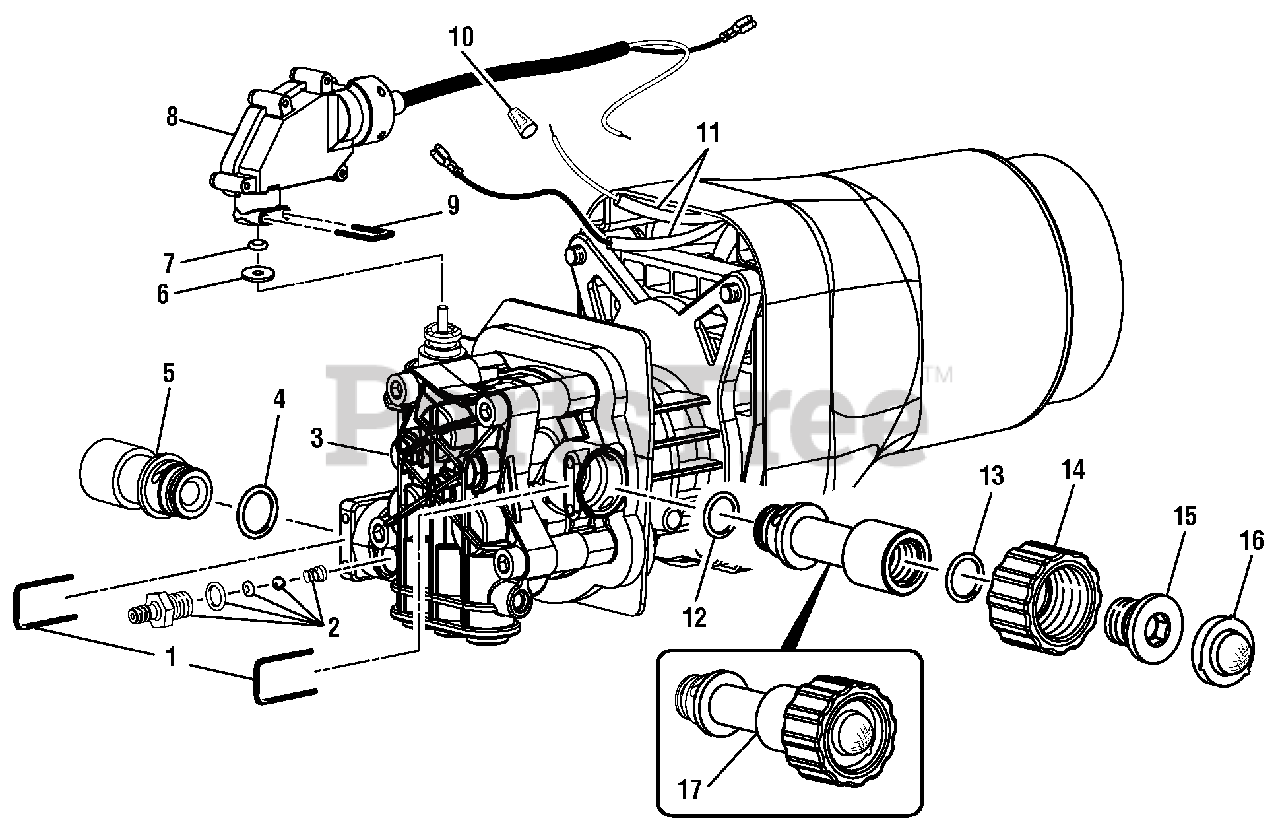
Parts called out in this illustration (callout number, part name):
2	Detergent Nipple Assembly
3	Motor and Pump Assembly
5	Outlet Tube Assembly
6	Washer (Brass)
7	O-Ring
8	Pressure Switch
14	Water Inlet Connector
15	Water Inlet Screw Nut
16	Water Inlet Filter
17	Inlet Tube Assembly
